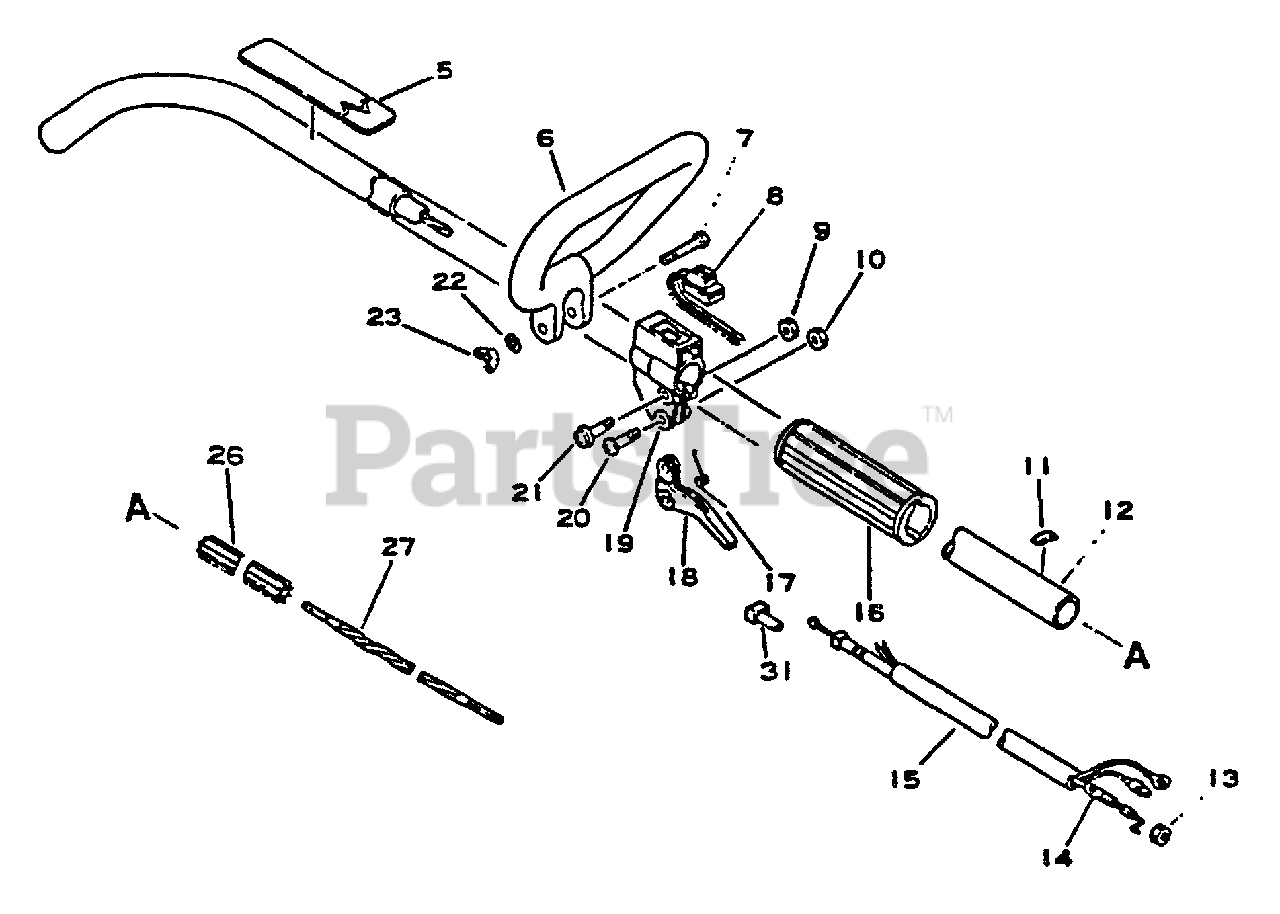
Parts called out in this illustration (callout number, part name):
5	LABEL - CAUTION
6	HANDLE
7	BOLT - 6×40
8	IGNITION SWITCH ASSY
9	NUT M5
10	LOCKNUT - 5
11	LABEL - ALIGNMENT
12	MAIN PIPE ASSY
14	CABLE, THROTTLE
16	GRIP, HANDLE
17	SPRING, THROTTLE
18	TRIGGER, THROTTLE
19	BRACKET, THROTTLE CONTROL
21	SCREW 5×28
22	WASHER 6.5×11.5×0.8
23	NUT, WING 6
26	LINER - FLEXIBLE
27	DRIVESHAFT - FLEXIBLE
31	GUIDE, CABLE
